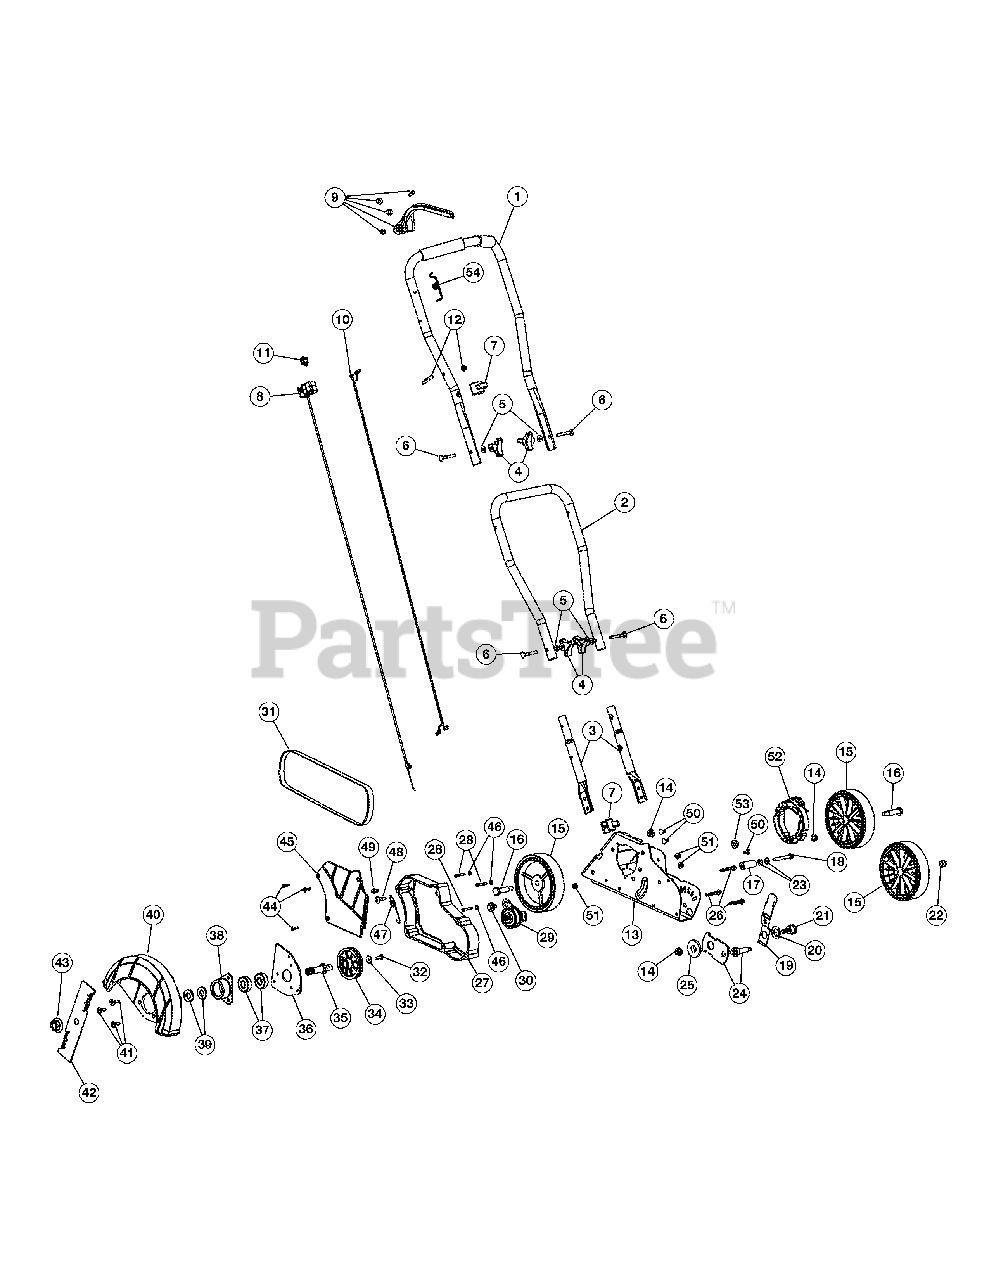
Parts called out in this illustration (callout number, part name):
1	Upper Handle
2	Middle Handle
3	Handle Extension
4	Handle Knob
5	Washer
7	Cable Guide
8	Throttle Cable
9	Throttle Lever w/Hardware
10	Lead Wire
11	On/Off Switch
12	Starter Rope Guide
13	Edger Frame
14	Lock Nut
16	Wheel Bolt
17	Spacer
18	Spacer Screw
19	Height Adjustment Lever Assembly
20	Washer
21	Shoulder Screw
23	Washer
24	Pivot Arm
25	Height Adjustment Spacer
26	Spindle Plate Screw
27	Spindle Spacer
29	Idler Pulley Assembly
30	Shoulder Screw
32	Screw
33	Washer
34	Pulley
35	Blade Spindle
36	Spindle Plate
37	Bearing
38	Bearing Cup
39	Washer
40	Blade Guard
41	Screw
42	Edger Blade
45	Belt Cover
47	Spring
49	Screw
50	Bolt
52	Spacer
54	Spring
